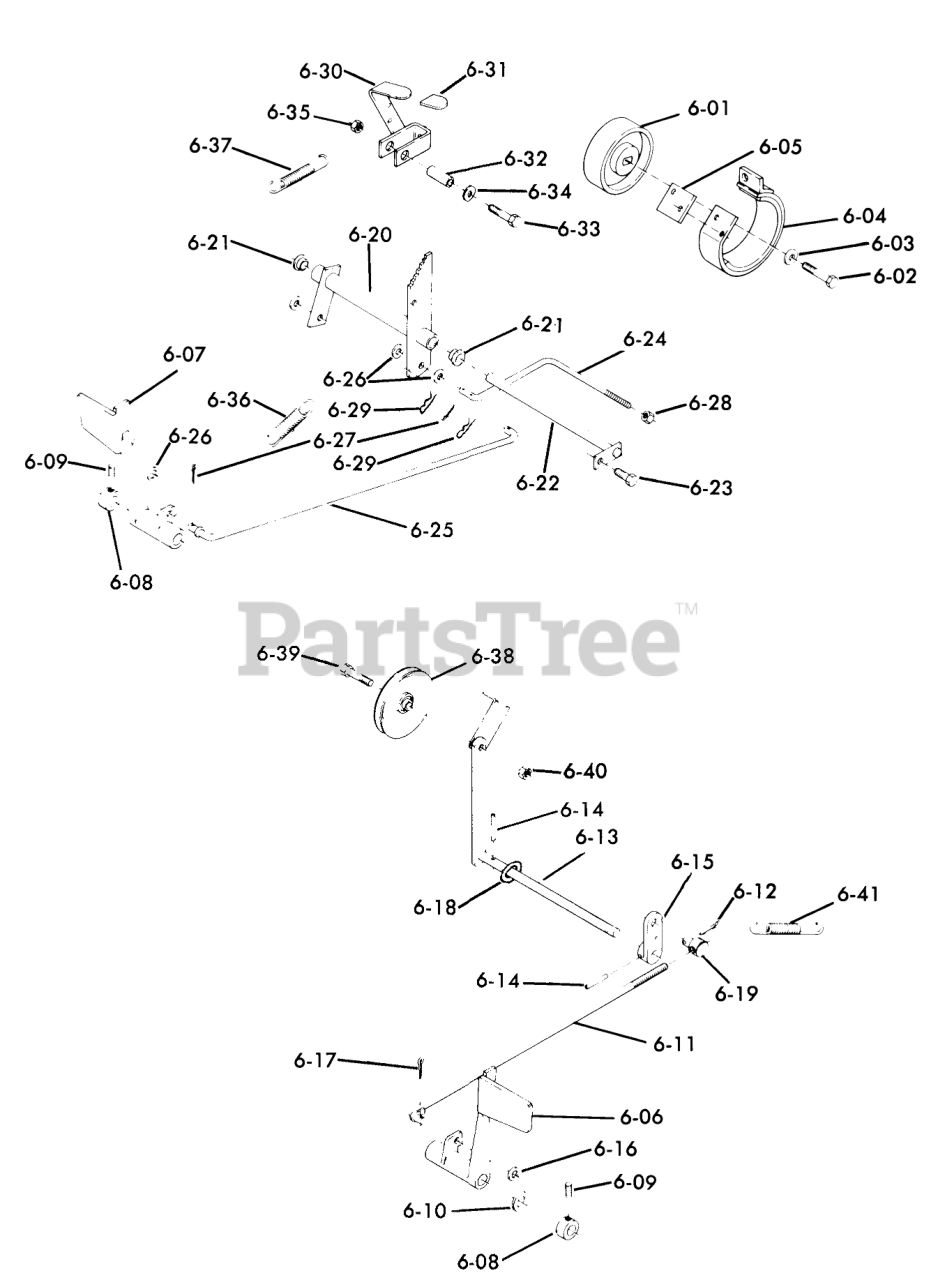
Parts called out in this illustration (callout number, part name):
6-01	Brake Drum
6-02	Bolt
6-03	WASHER
6-04	BRAKE BAND ASM
6-05	Plate-Stop
6-06	Clutch Pedal
6-07	PEDAL-BRAKE R
6-08	Collar
6-09	SCREW-SET
6-10	WASHER-BOWED
6-11	ROD AND GUIDE ASM
6-13	Idler Arm Assembly
6-14	PIN-SPIROL
6-15	Clutch Pivot Arm
6-16	WASHER-NYLON
6-17	Pop Rivet
6-18	SHIM-WASHER
6-20	Bellcrank Assy
6-21	BUSHING-FLANGED
6-22	Rod Assy
6-23	SCREW
6-24	Brake Rod
6-26	WASHER-NYLON
6-27	Pop Rivet
6-28	NUT
6-29	Hairpin
6-30	Brake Lever Assy
6-31	GRIP
6-32	SPACER
6-33	Bolt
6-34	Washer
6-35	LOCKNUT-FLANGE
6-36	Spring
6-37	SPRING-EXTENSION
6-38	PULLEY-IDLER
6-39	HEX HD CAP SCREW
6-40	Nut
6-41	Spring
